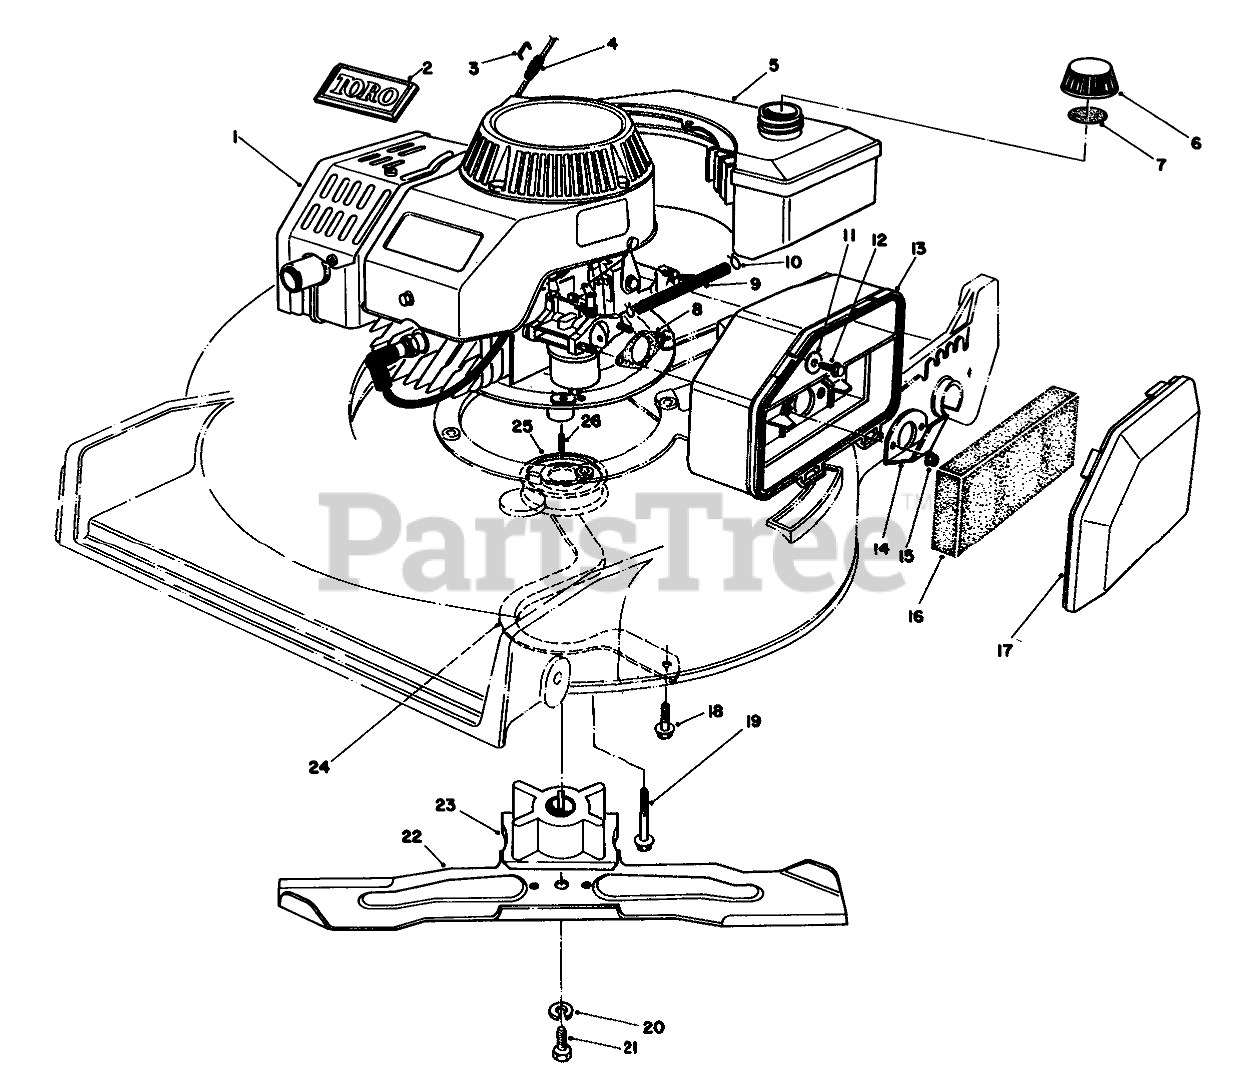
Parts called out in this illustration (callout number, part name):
1	Engine
2	TORO LOGO PLT
3	STAPLE
4	ROPE STOP
5	Gas Tank Assembly
6	Gas Cap Assembly (Incl. Ref. #7)
7	GAS CAP GASKET
8	GASKET-AIR CLEANER
9	FUEL LINE
10	CLAMP-HOSE
11	WASHER-FLAT
12	SCREW-HH
13	AIR CLEANER
14	SPIT BACK DEFLECTOR
15	NUT-LOCK
16	FILTER
17	AIR CLEANER COVER
18	Screw
19	SCREW-HHF
20	WASHER-LOCK
21	SCREW-BLADE
22	BLADE-21in
23	Retainer Blade
24	BELT GUIDE
25	PULLEY-DRIVER
26	KEY-SQUARE
